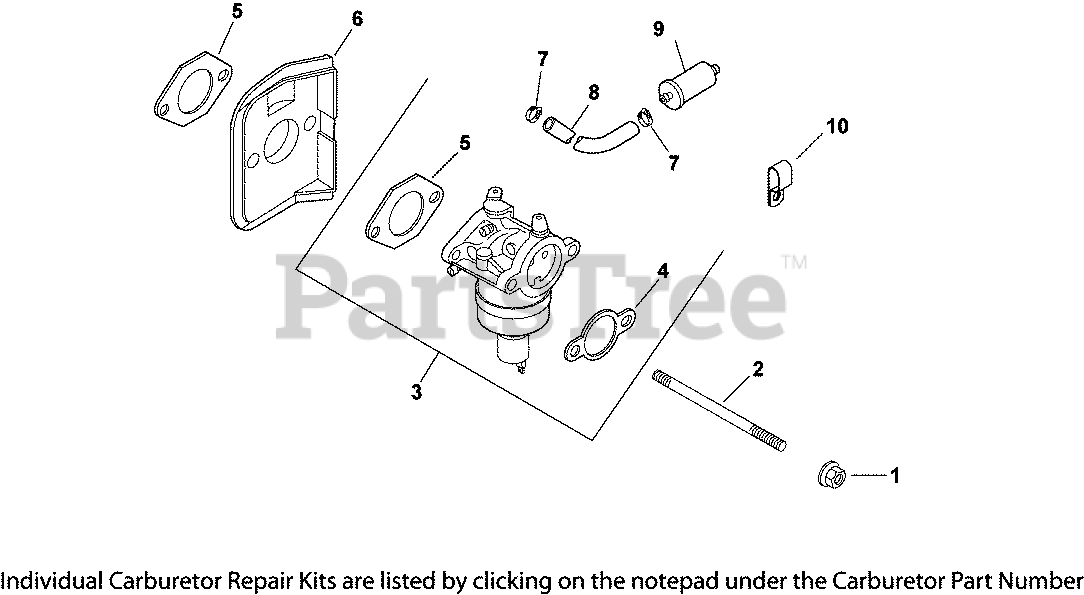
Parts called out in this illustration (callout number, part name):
1	NUT, FLG M6X1.0
2	STUD,M6X1.0X116
3	KIT, CARBURETOR w/GASKETS
4	GASKET, AIR CLEANER BASE
5	GASKET, CARBURETOR
6	DEFLECTOR, HEAT
7	CLAMP, HOSE (KM)-USE 25 237 31-S
8	LINE, FLEXIBLE FUEL
9	FILTR,FUEL 75 MICRON (GRAVTY FEED)
10	CLIP, CABLE
